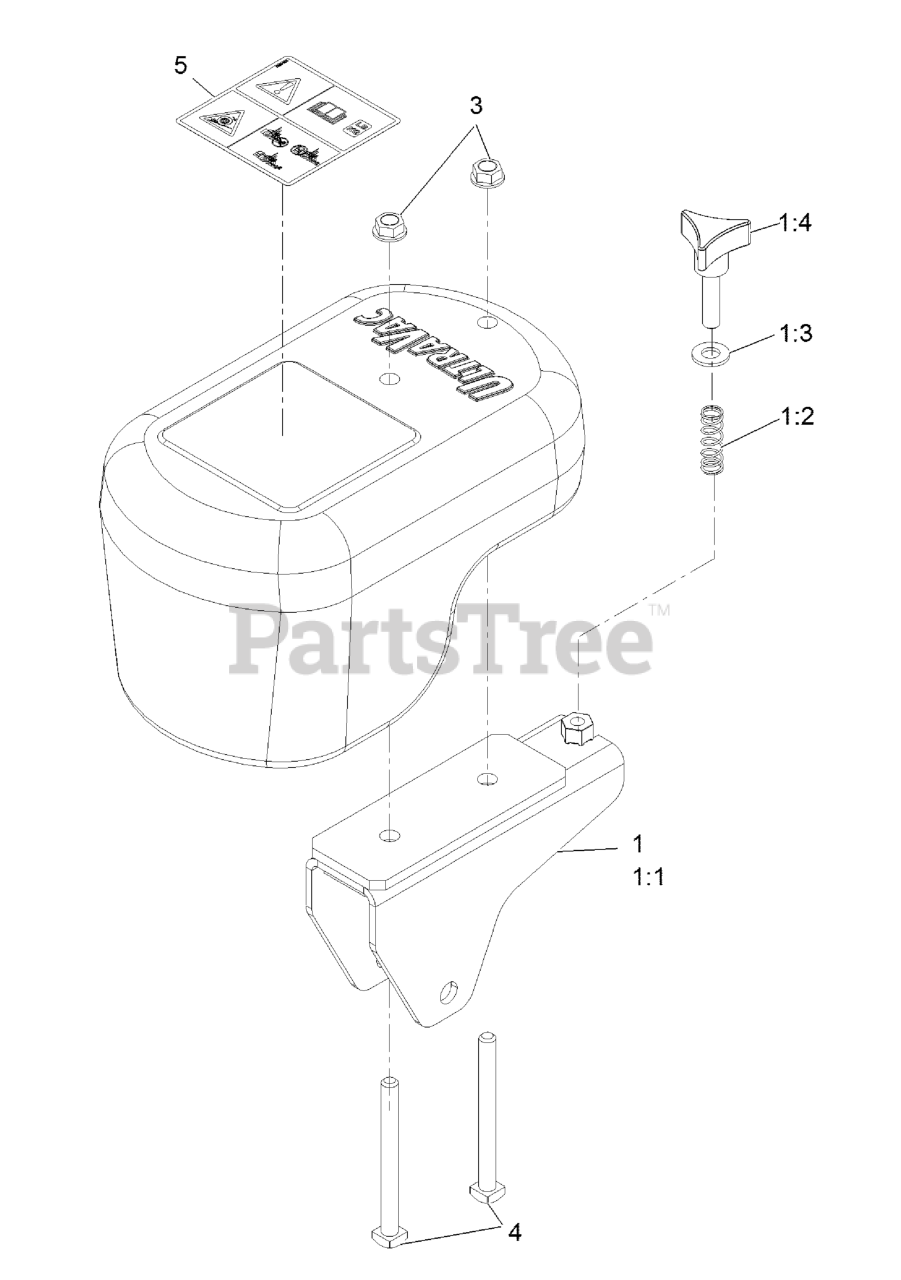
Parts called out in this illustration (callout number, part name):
1	ASM,CASTER WEIGHT BRACKET
1:1	WLD,CASTER WEIGHT BRACKET
1:3	WASHER-FLAT
3	NUT-HHF, WHIZ
4	BOLT, SQUARE HEAD YZ
5	DECAL-WARNING, TRACTION
